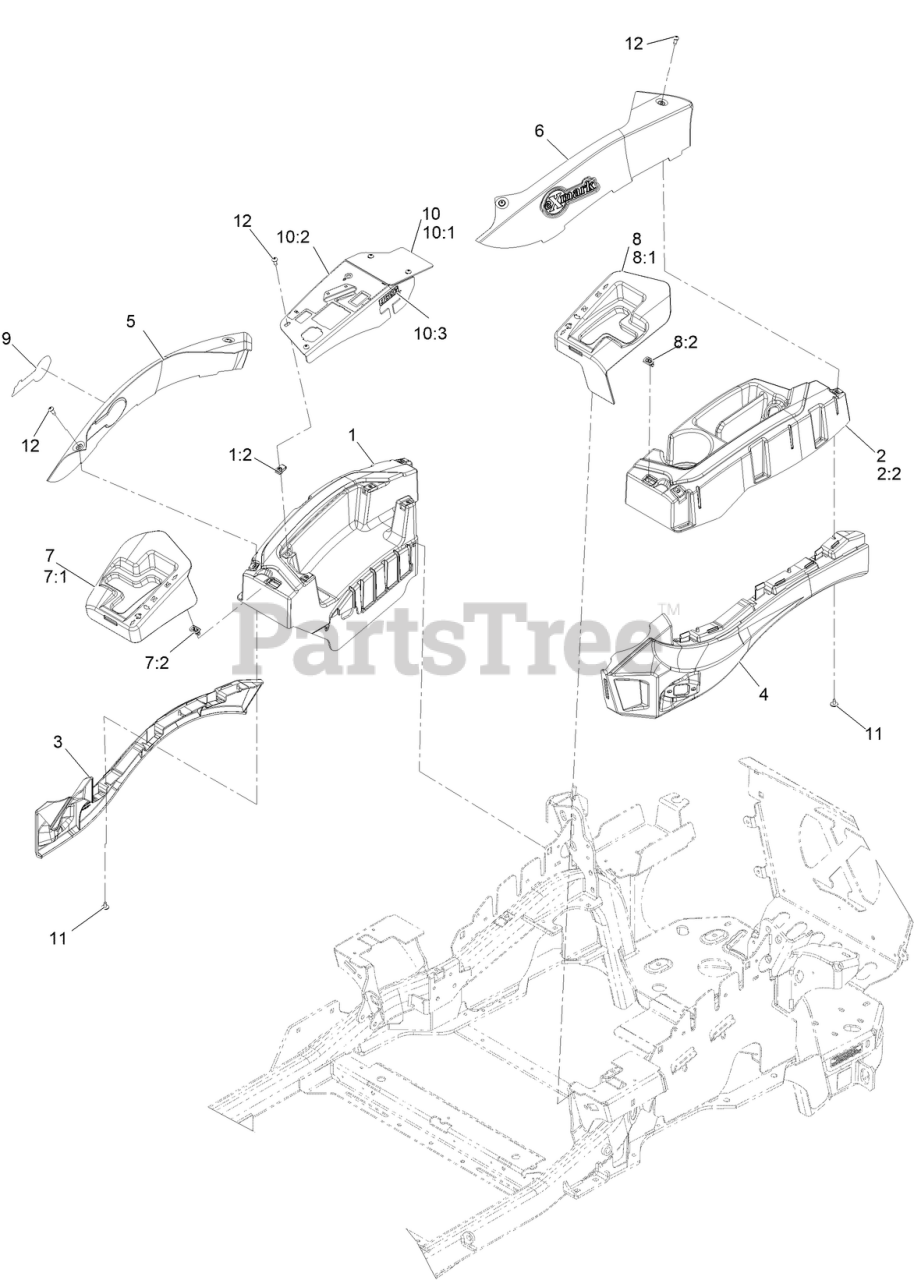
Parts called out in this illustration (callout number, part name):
1	CONSOLE-RH
2	CONSOLE-LH
3	FENDER-RH
4	FENDER-LH
5	PANEL-SIDEPOD ACCENT
6	Panel-Sidepod Accent [red]
7	ASM-MOTION CONTROL COVER RH
7:1	Cover-RH Motion Control
7:2	Clip-Trim
8	ASM-MOTION CONTROL COVER LH
8:1	Cover-LH Motion Control
8:2	Clip-Trim
9	DECAL-EXMARK LOGO
10	ASM-Console Panel W/Decals
10:1	PANEL-CONSOLE
10:2	DECAL-CONTROL PANEL EFI
10:3	DECAL-FUSES
11	SCREW-TORX
12	SCREW-TPH THD FORM
